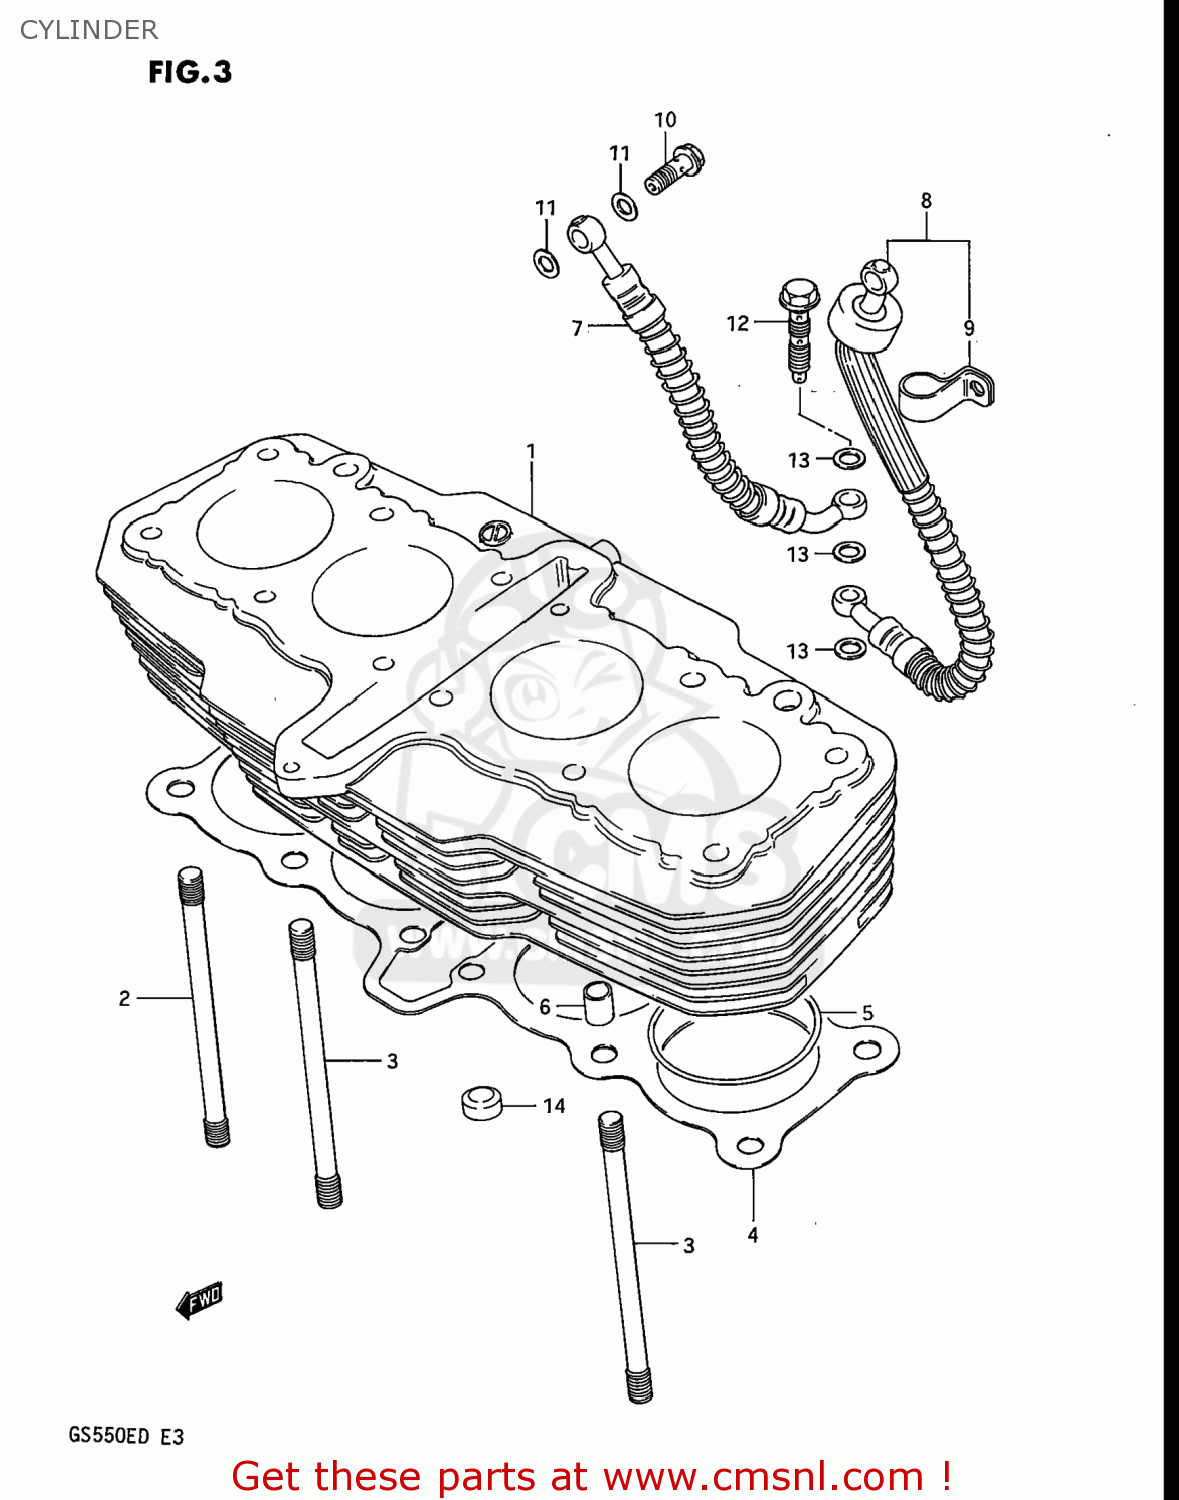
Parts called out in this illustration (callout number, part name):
1	CYLINDER
2	STUD
3	STUD
4	GASKET,CYLINDER (MCA)
5	O RING(D:2,ID:61)
6	PIN
7	HOSE,OIL CRANKCASE,R
8	HOSE,OIL
9	CLAMP,OIL HOSE CRANKCASE
10	BOLT UNION
11	GASKET 8.2X14X1 (NAS)
12	BOLT,OIL PIPE
13	WASHER
14	PAD,CYLINDER HEAD
